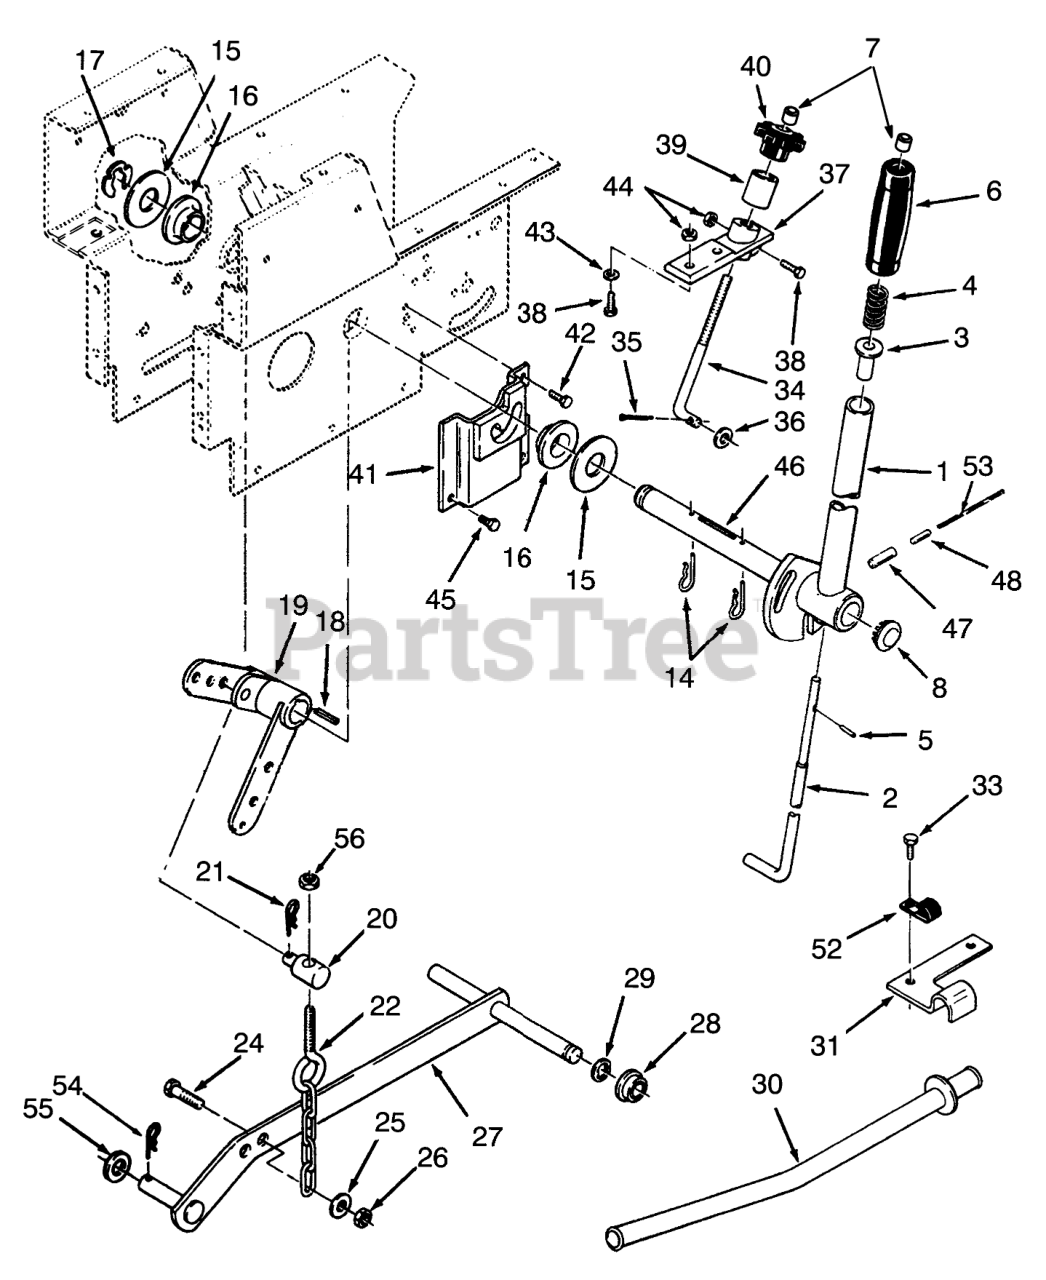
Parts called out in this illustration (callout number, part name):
1	Lever-Lift (Incl. Ref. #46, 47, & 48)
2	ROD-LATCH LIFT
3	RETAINER-SPRING
4	SPRING-COMPRESSION
5	PIN-SPIROL
6	HANDGRIP
7	CAP-ROD, PLUNGER
8	PLUG
14	Pin-Cotter
15	WASHER-FLAT
16	BEARING-FLANGE
17	Retainer
18	KEY-SQUARE
19	LIFT LEVER ASM
20	TRUNNION-LIFT
21	PIN-HAIR
22	CHAIN-LIFT
24	SCREW-HH
25	WASHER-PLAIN
26	NUT-LOCK, NI
27	Bar-Lift
28	BUSHING
29	E Ring
30	TUBE ASSY COMPLET R
31	CLAMP-CONDUIT R
33	SCREW-HH, LOCK
34	ROD-HEIGHT CONTROL
35	PIN-COTTER
36	WASHER-FLAT
37	Casting
38	SCREW-HH
39	Sleeve
40	KNOB-LIFT CONTROL
41	Latch Bracket
42	Bolt
43	WASHER-PLAIN
44	NUT-LOCK, NI
45	Bolt
46	SHAFT-LIFT LEVER
47	PIN-SPRING
48	PIN-ROLL
52	CLIP
53	Lock Wire
54	Hairpin Cotter
55	WASHER-FLAT
56	NUT-LOCK, NI
